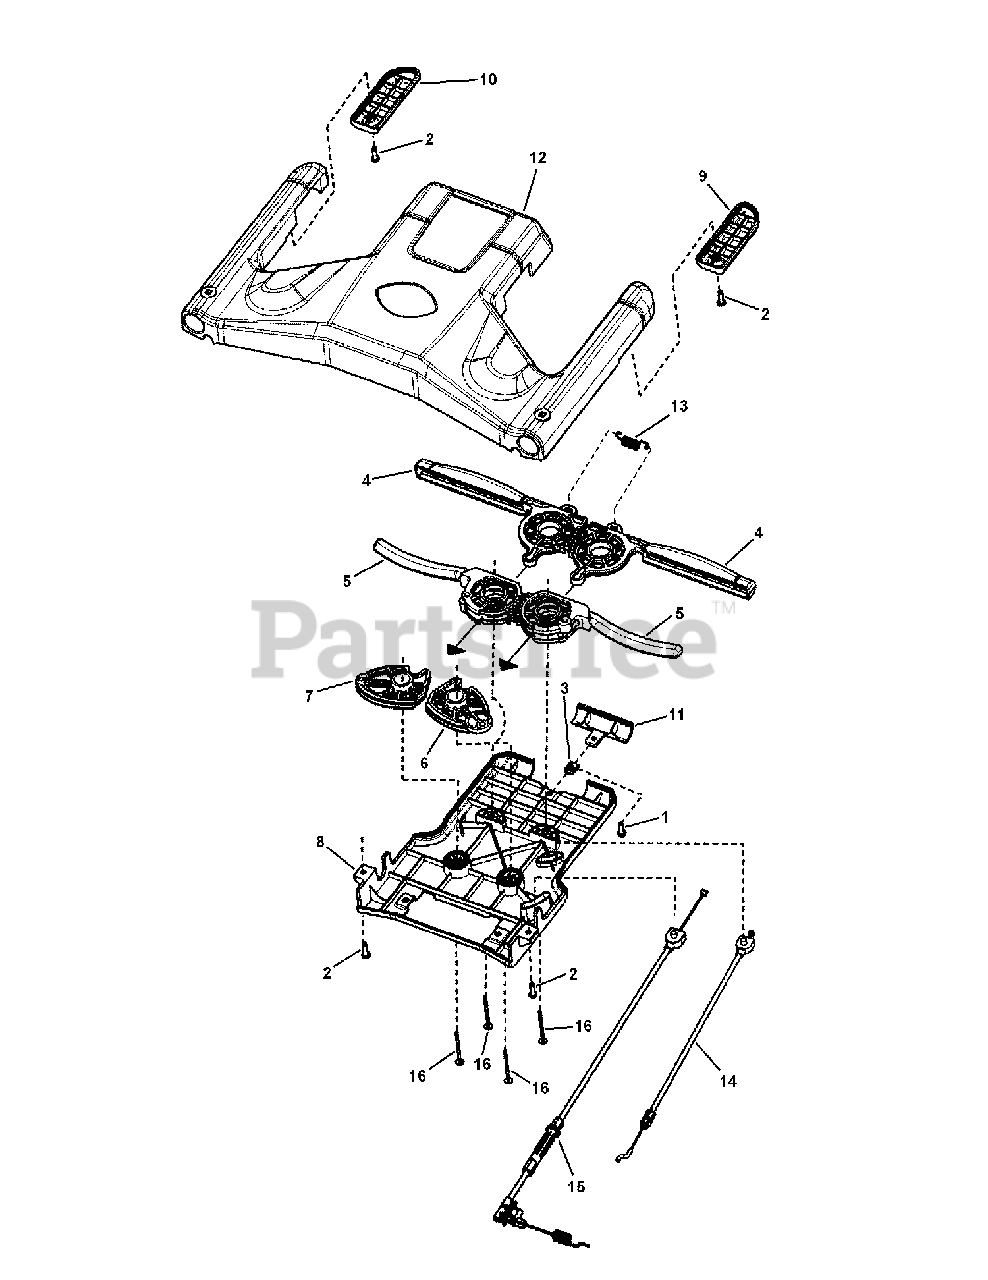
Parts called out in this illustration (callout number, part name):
1	SCREW, #10-24 x 5/8" Hex Washer Self-Tap
2	SCREW, #10-16 x 3/4" Pan Head Self-Tap, Combo
3	NUT, #10-24 Retainer Speed w/extrusion
4	LEVER, Drive Control
5	LEVER, OPC, Control
6	CAM, Drive, LH
7	CAM, Drive, RH
8	CONTROL PANEL, Bottom, MY Mower
9	PANEL, Bottom Control, WBM, RH
10	PANEL, Bottom Control, WBM, LH
11	PANEL, Access, Maintenance Reminder
12	PANEL, Top Control
13	SPRING, Tension, Drive Control
14	CABLE, OPC, 2010 NXT
15	CABLE, Drive Control, 2010 NXT FWD
16	SCREW, #10-16 x 2" Hi-Lo Cross Pan Head
